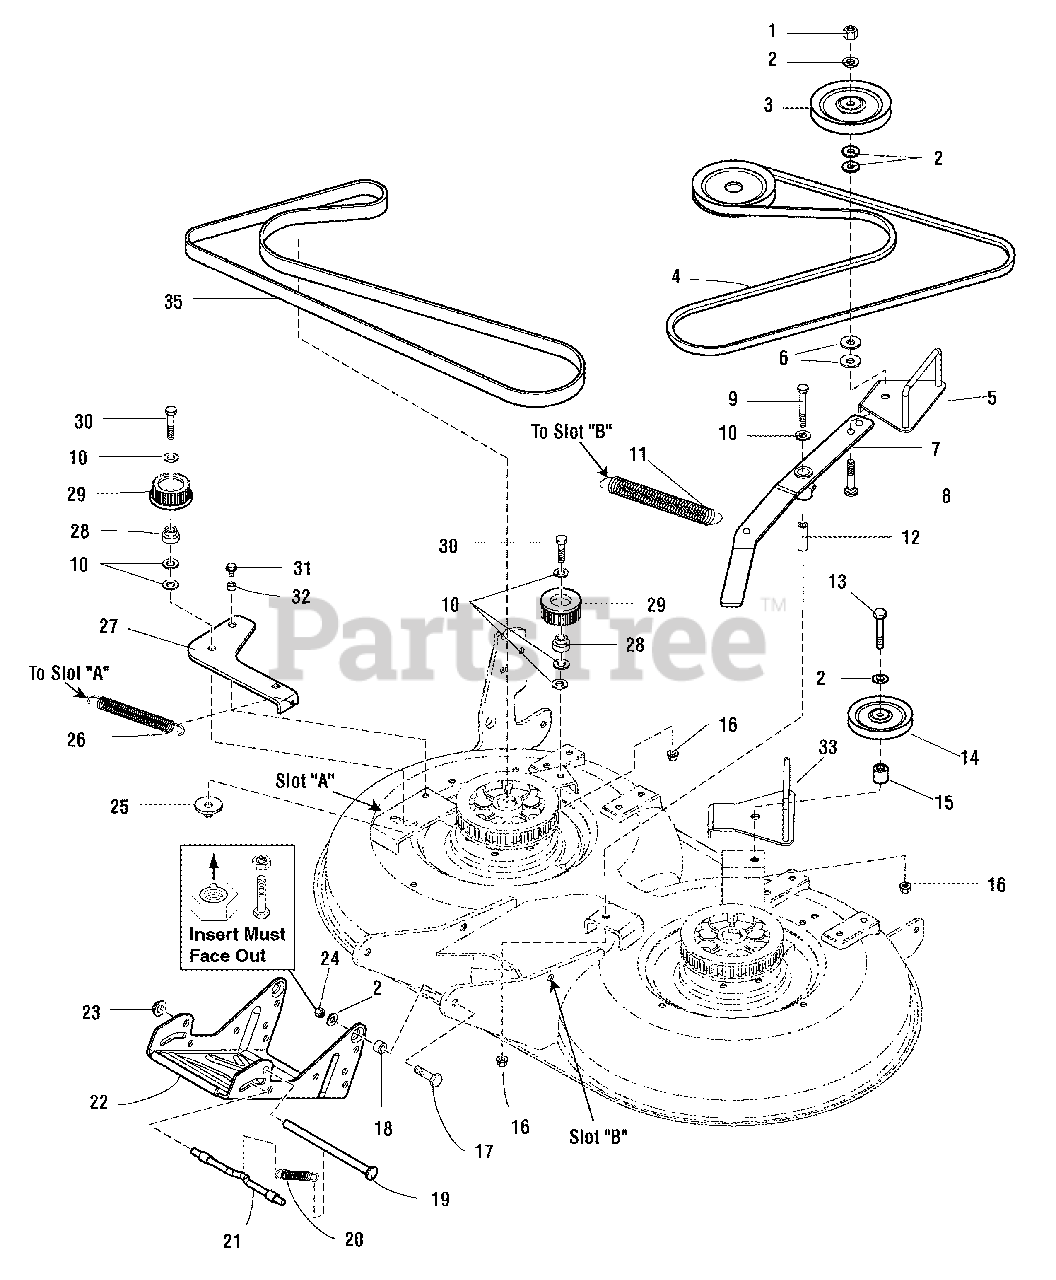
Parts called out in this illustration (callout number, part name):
1	NUT, Hex Lock Esna Light, 3/8-16
2	WASHER, 3/8
3	PULLEY, Idler
4	V-BELT, Mower Drive (82.0 EL, HA Sect.)
5	BELT GUIDE
6	WASHER, 3/8
7	ARM ASSEMBLY, Idler with Bushings & Fitting, 38 Tooth
8	CARRIAGE BOLT, 3/8-16 x 2-1/4
9	CAPSCREW, Hex Head, 3/8-16 x 3
10	WASHER, 3/8
11	SPRING, Extension, Idler Arm
12	SPACER, Hardened
13	CAPSCREW, Hex Head, 3/8-16 x 2-1/4
14	PULLEY
15	SPACER
16	NUT, Hex Flange Whiz Lock, Large, 3/8-16
17	CAPSCREW, Hex Head, 3/8-16 x 1-1/2
18	SPACER
19	ROD, Mower Hitch
20	SPRING
21	ROD, Latch
22	HITCH, Mower
23	NUT, Push
24	NUT, Hex Toplock Sprial Flange, 3/8-16
25	WASHER & NUT ASSEMBLY, 3/8 x 1-1/2
26	SPRING, Extension
27	ARM, Idler
28	HUB
29	PULLEY, Idler
30	BOLT, Hex Flange 3/8-16 x 2
31	CAPSCREW, Taptite Hex Washer Head, 5/16-18 x 1/2
32	SPACER
33	BELT GUIDE
35	BELT, Timing, 38 Tooth, Arbor Drive
